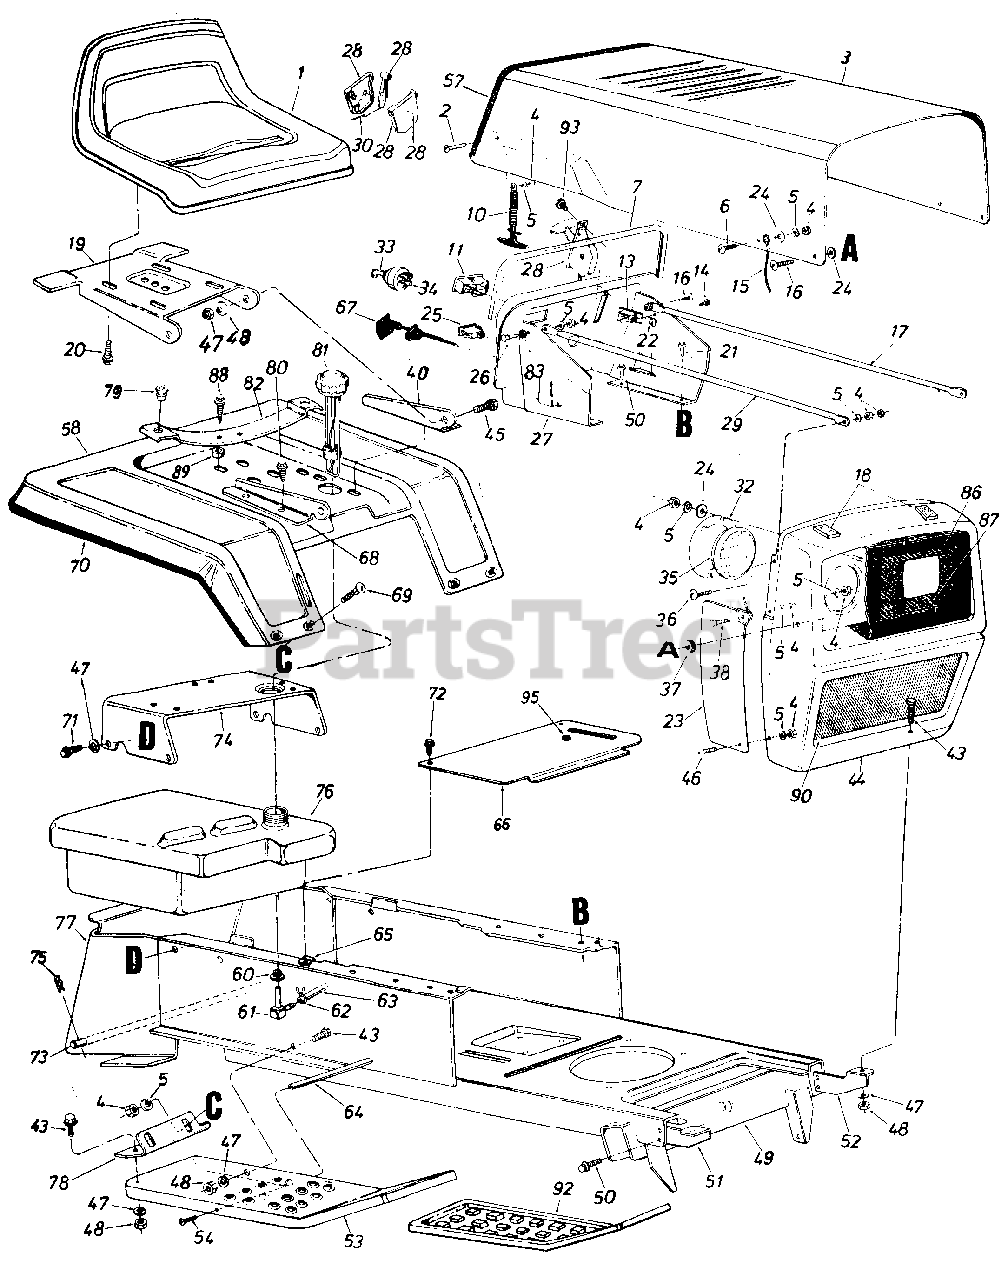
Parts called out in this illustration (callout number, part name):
1	Seat Assembly
2	Truss Mach. Scr. 1/4-20 x .50" Lg.
5	L-Wash. 1/4" Scr.
6	Truss Mach. Scr. 1/4-20 x .50" Lg.
7	Vinyl Molding Strip-29"
10	Hood Latch Ass'y.
11	Ammeter
13	Circuit Breaker 8 Amp.
14	Hex Tap Scr. #10 x .50" Lg.
16	Truss Mach. Scr. 1/4-20 x .75" Lg.
17	Grille Positioning Rod
18	PVC Foam Strip 1/2 x 1.00" x 2.00" Lg.
19	Seat Pivot Brkt.
20	Hex Wash. Hd. AB-Tap Scr. 3/8 x .75" Lg.
21	Hex Thd. Rolling Scr. 1/4" x .50" Lg.
22	Speed Nut #10Z
23	Grille Side Panel-R.H.
24	Fl-Wash. 1/4" I.D.
25	Light Switch
26	Truss Hd. Scr. 1/4-20 x 1.00" Lg.
27	Dash Panel Ass'y.
28	Throttle Control Box Comp.
29	Grille Positioning Rod
30	Throttle Control Cable
32	Head Lamp Retainer
33	Ignition Key
34	Ignition Switch
35	Head Lamp
36	Truss Machine Scr. 1/4-20 x .75" Lg.
37	Rubber Wash. .50" I.D. x 1.00 O.D. x .25 Thk.
38	Truss Mach. Scr. 1/4-20 x .50" Lg.
40	Seat Bracket-L.H.
43	Hex Scr. 5/16-18 x .75" Lg.
44	Grille Ass'y.
45	Shld. Bolt .437 Dia. x .162 Lg.
46	Truss Mach. Scr. 1/4-20 x .50" Lg.
47	L-Wash. 5116" I.D.
48	Hex Nut 5/16-18 Thd.
49	Lower Frame Ass'y.
50	Hex Thd. Rolling Scr. 5/16" x.75" Lg.
51	Grille Mount Brkt.-R.H.
52	Grille Mount Brkt.-L.H.
53	Running Board-R.H.
54	Truss Mach. Scr. 5/16-18 x .75" Lg.
57	Vinyl Moulding Strip-30"
61	90ø Nipple
62	Hose Clamp 3/8"
63	Gas Line 46" Lg.
64	Running Board Rod
65	Speed Nut #10-24
66	Transmission Cover Ass'y.
67	Choke Control Comp.
68	Seat Bracket-R.H.
69	Carr. Bolt 1/4-20 x 50n Lg.
70	Trim Strip-81n Lg.
71	Hex Thd. Rolling Scr. 5/16-24 x .75" Lg.
72	Truss Hd. Scr. #10 x 50n Lg.
74	Seat Mounting Channel
75	Internal Cotter Pin
77	Hitch Plate
82	Seat Spring
83	External Wash. 1/4" I.D.
86	Headlight Bezel
87	Hex Wash. Hd. F-Tap Scr. #8-32 x .38" Lg.
88	Hex Self-Tap Scr. 5/16-18 x 1.25" Lg.
89	Spacer
90	Grille Screen
93	Truss Mach. AB-Tap Scr. #10 x 50n Lg.
95	Snap Bushing
